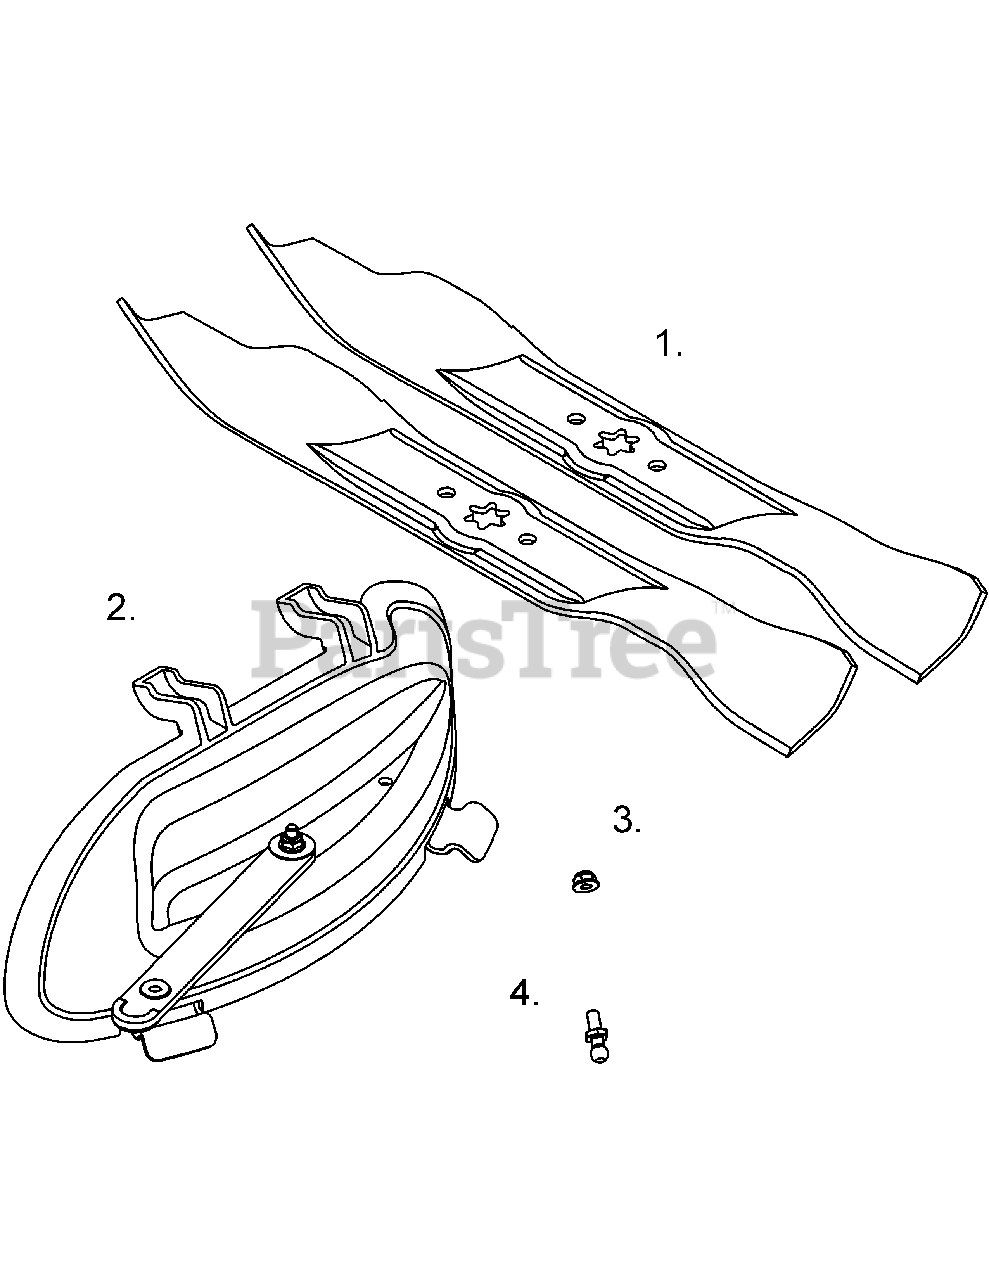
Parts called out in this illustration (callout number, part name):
1	Blade, Mulching
2	Plug, Deck Mulch Assembly
4	Pin, Grass Catcher
